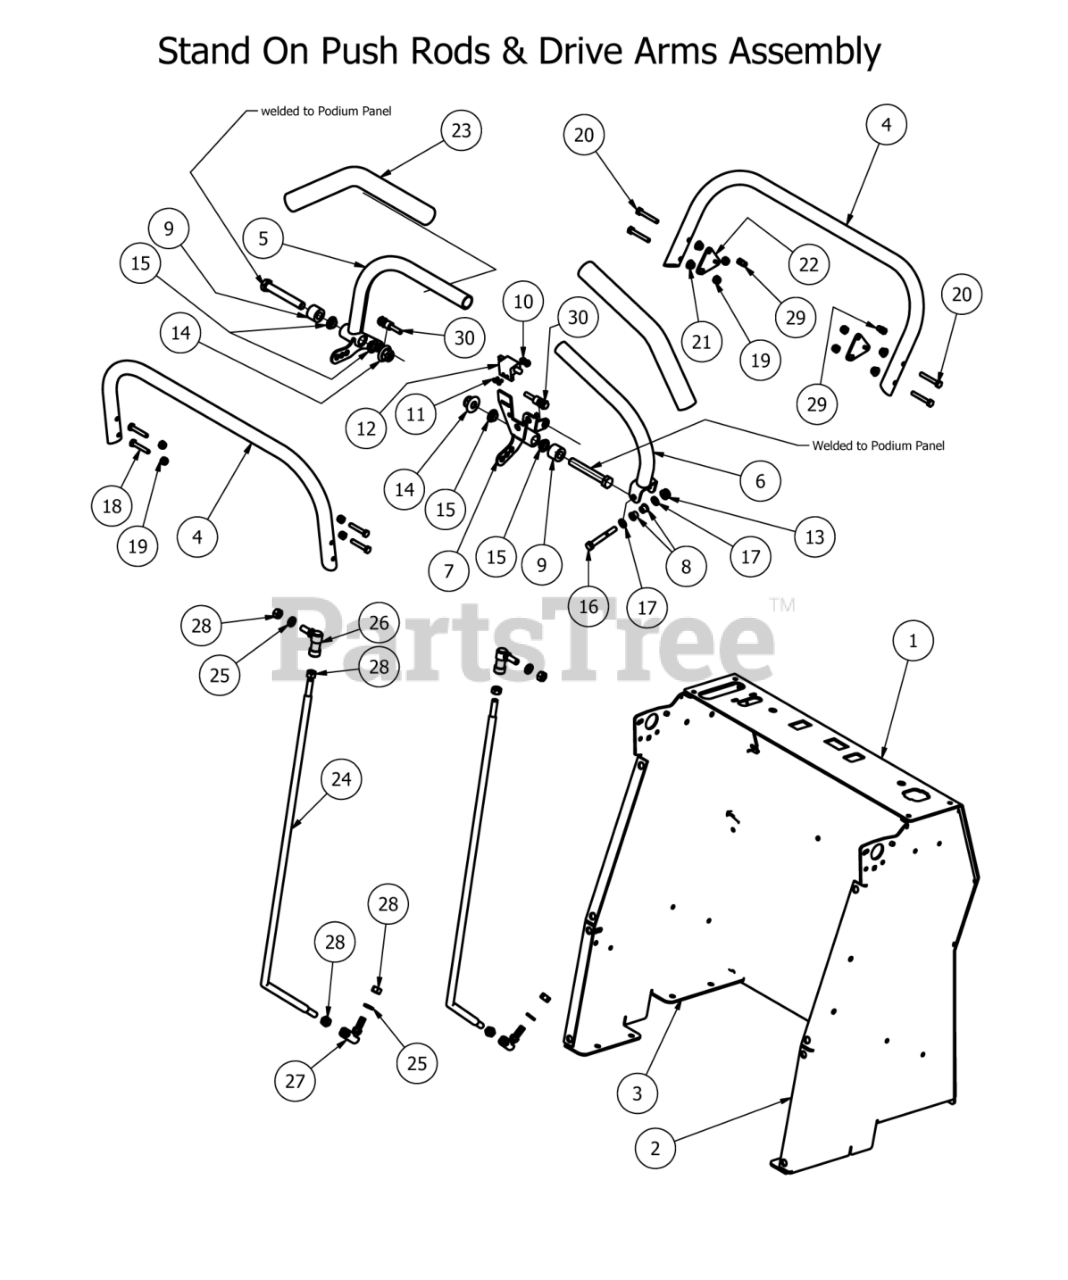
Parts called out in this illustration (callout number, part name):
1	Podium Front Panel
2	Podium Panel Right Side
3	Podium Panel Left Side
4	Support Handle Stand Up (Front & Back)
5	Left Steering Handle Assembly
6	Right Steering Handle Assembly
7	Safety Kill Switch Assembly Bracket
8	Stand On Flange Bushing-Steering Arms
9	Steering Arm Spacer- Stand On
10	10-24 Nylon Insert Locknut
11	1024 X 5/8" Buttonhead Bolt
12	Safety Switch
13	5/16-18 Nylon Flange Nut
14	1/2-13 Nylon Flange Nut-Orange
15	Bushing for 2012 Drive Arms
16	5/16" x 2 1/2" Bolt
17	1/4" Flat Washer
18	1/4-20 x 1 1/2" Bolt
19	1/4" Nylock Nut
20	1/4-20x 1-3/4" Hex Bolt
21	1/4-20 Hex Flange Nuts Zinc w/Serrations
22	Neutral Safety Tab
23	Black Steering Grip
24	Push Rod Stand On
25	3/8" Lock Washer
26	3/8-24 Quick Release Ball Joint
27	3/8-24 Ball Joint
28	3/8" Fine Threaded Jam Nut
29	Magnet-Steering Arm-Stand On
30	Safety Switch Harness
